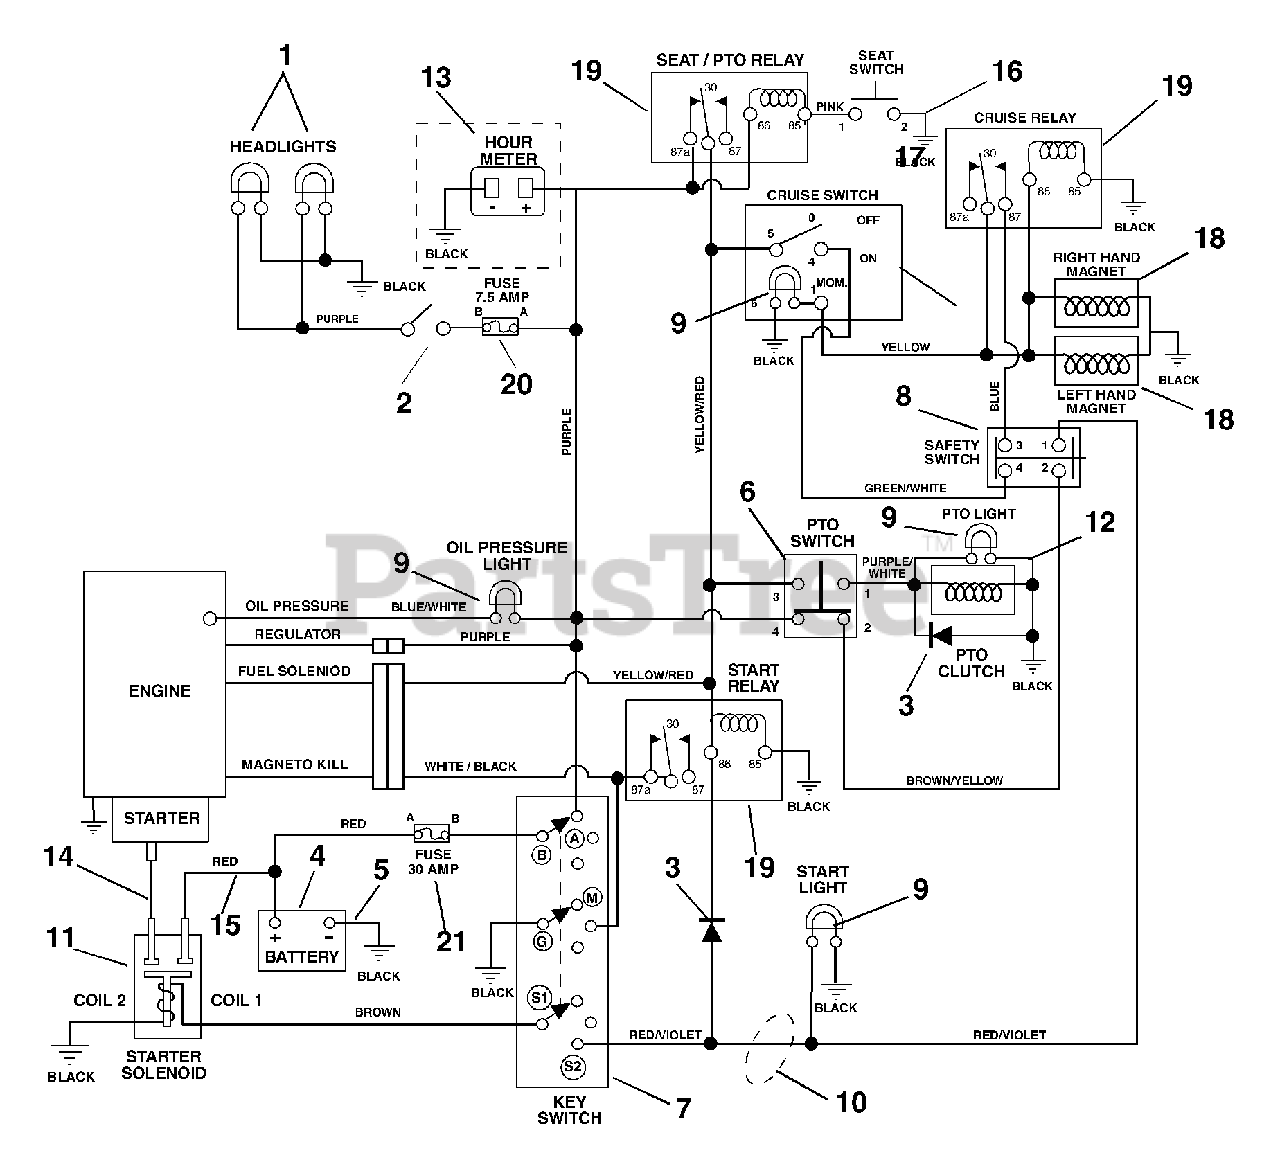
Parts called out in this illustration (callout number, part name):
1	HEADLIGHT BULB, 1156
2	SWITCH - LIGHT
3	MOLDED DIODE PLUG 1 AMP
4	BATTERY W/TUBE
5	GROUND CABLE .31X22.00X.31
6	PTO KNOB/ SWITCH ASSY
7	KEY SWITCH
8	SWITCH,INTERLOCK
9	BULB, #194
10	HARNESS-WIRING,HIGH SIERRA
11	SOLENOID
12	CLUTCH, ELECTRIC - WARNER
13	HOUR METER
14	START CABLE 22"
15	STARTER CABLE 6.75"
16	SWITCH- SEAT
17	SWITCH - CRUISE
19	RELAY
20	FUSE, 7.5 AMP
21	FUSE, 30 AMP.
